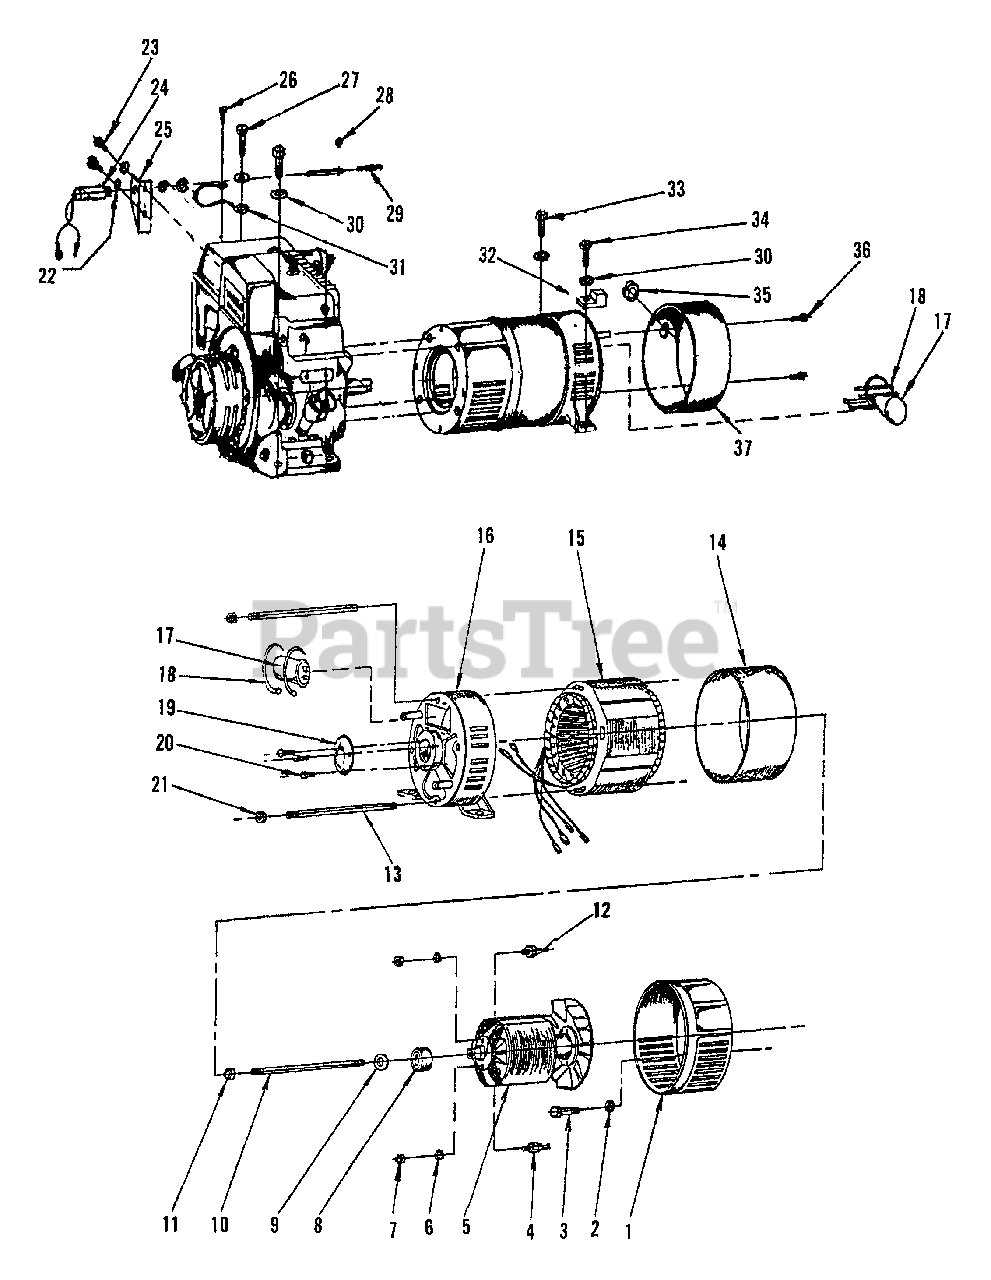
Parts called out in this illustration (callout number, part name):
1	DRIVE END ADAPTER CASTING
2	WASHER, LOCK 3×8
3	SCREW - 3/8-16×1.00" -- HEX HEAD CAP
4	DIODE
5	ROTOR ASSY
8	BEARING
9	LOCKWASHER - 5/16"
10	ROTOR THRU BOLT
11	NUT - 5/16-24 -- KEPS
12	DIODE
13	BOLT, STATOR
14	BAND, COVER
15	STATOR ASSY
16	CASTING, BEARING
17	CAPACITOR - 50UF 370V
18	TIE, CABLE
19	COVER, BEARING
20	SCREW #10×24×1×2
21	NUT - 1/4-20 -- KEPS
22	WASHER, LOCK 1×4
23	BKT, MTG SCREW SOLENOID
24	SOLENOID ASSY
25	BRACKET, ECHO-MIZER
26	SCREW - 10-24
27	BOLT - 5/16-18×1-1/2"
28	PIN, COTTER
29	SPRING, ECHO-MIZER
30	WASHER, LOCK 5×16
31	LEAD - GROUND
32	LUG, GROUND - 1/0-14 CU/AL
33	5/16-18×5/8 HHS
34	5/16-18×7/8 HHS
35	GROMMET
36	SCREW - 10-24 -- SLOT HEAD
37	COVER, END
